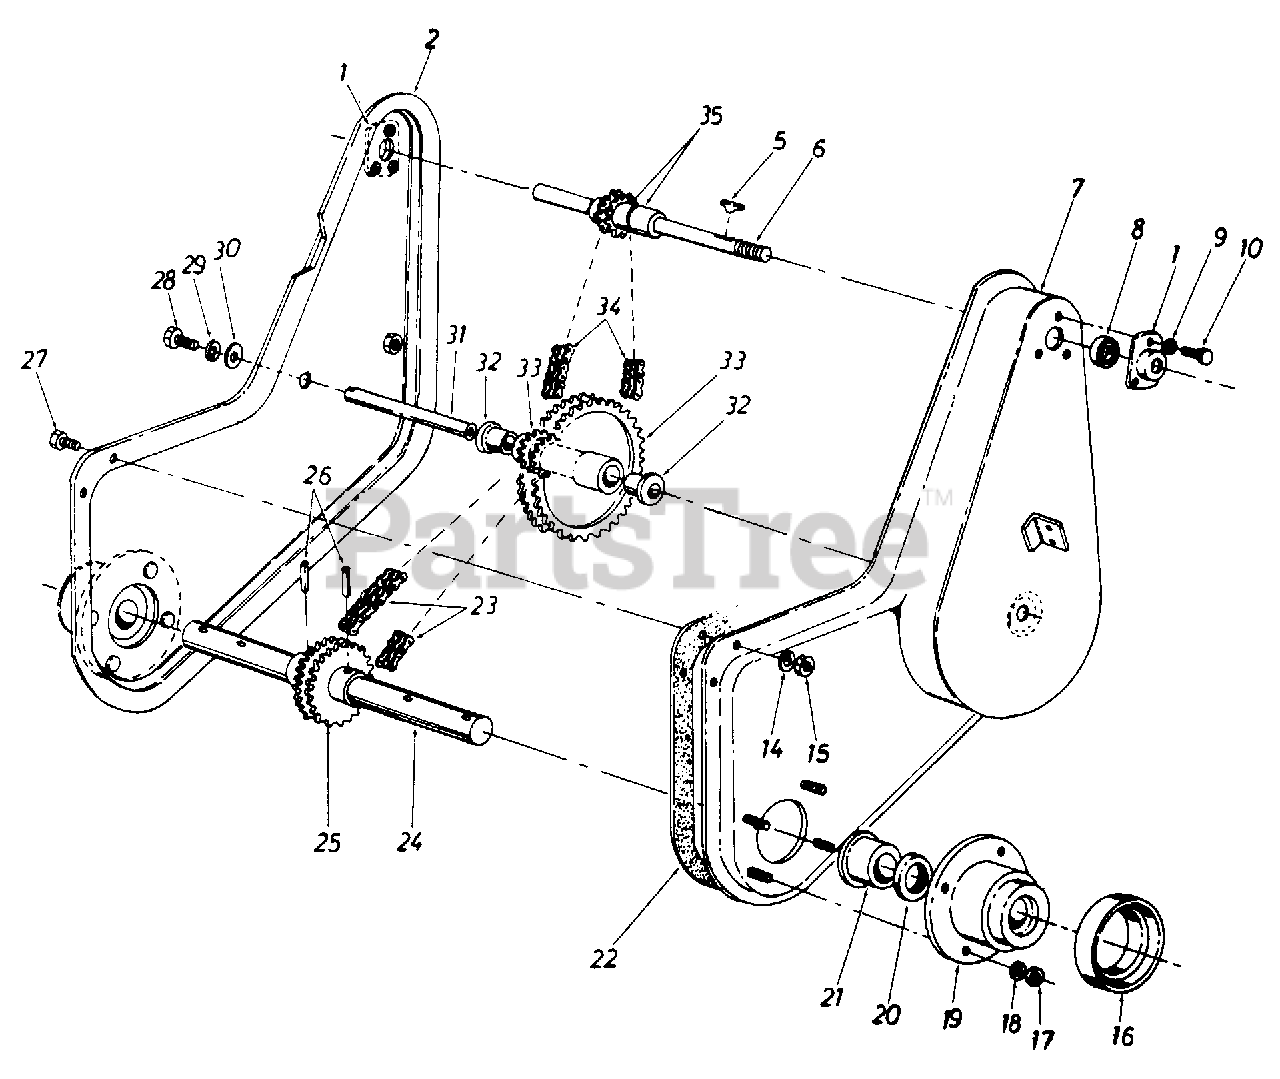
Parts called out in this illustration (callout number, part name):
1	Bearing Housing 1.375" Dia.
2	Housing Assembly R.H.
5	#6 Hi-Pro Key 5/32" x .62"-Lg.
6	Input Shaft Assembly
9	L-Wash. 1/41" I.D.
10	Hex Bolt 1/4-20 x .62" Lg.
14	L-Wash. 1/4" I.D.*
15	Hex Cent. L-Nut 1/4-20 Thd.
16	Dust Cap Cover
17	Hex Cent. L-Nut 5/16-18 Thd.
18	L-Wash. 5/16" I.D.*
19	Cast Bearing Housing
20	Oil Seal
21	Flange Bearing 1.25" I.D. x 1.75" O.D.
22	Gasket
23	Roller Chain #40-2 x 34.0 0 Lg.
24	Tine Shaft
25	Double Sprocket T24-2 0 Teeth 1/2" Pitch
26	Spiral Pin 3/8n Dia. x 2.00"-Lg.
27	Hex Bolt 1/4-20 x .62" Lg.
28	Hex Bolt 5/16-18 x .75" Lg.
29	L-Wash. 5/16" I.D.
30	Fl-Wash. 5/16" I.D.
31	Sprocket Shaft
32	Flange Bearing .62" I.D. x .75" O.D.
33	Double Sprocket Assembly
34	Roller Chain #35-2 x 36.75"-Lg.
35	Spacer 5/8" I.D. x 7/8" O.D.
